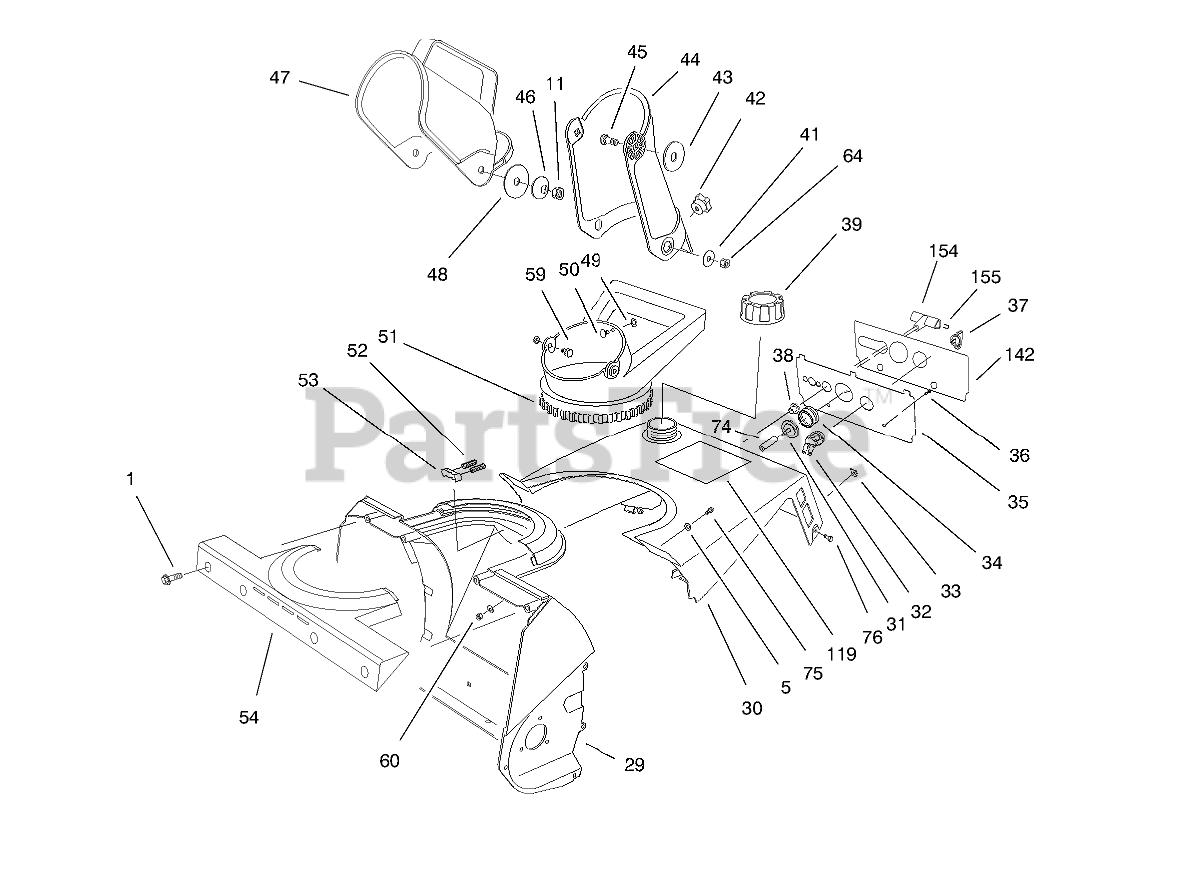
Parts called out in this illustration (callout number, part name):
1	SCREW-PLASTIC
5	WASHER-FLAT
11	NUT-LOCK, NI
29	HOUSING
30	Shroud-Upper
31	BODY-PRIMER
32	SWITCH
34	BULB-PRIMER
35	Panel-Control
36	SCREW-SHWH, THREAD FORMING
37	KEY-IGNITION
38	GUIDE-ROPE, STARTER
39	CAP-FUEL ASM
41	WASHER-FLAT
42	KNOB-CHUTE
43	WASHER-RUBBER
44	Chute
45	BOLT-CARR
46	WASHER-BELLEVILLE
47	DEFLECTOR-CHUTE
48	WASHER-FLAT
49	PUSHNUT-RETAINER, BOLT
50	SCREW-CARR
51	HANDLE-CHUTE
52	SPRING-COMPRESSION
53	DETENT-CHUTE
54	RETAINER-CHUTE
59	SCREW-HH
60	NUT-LOCK, NI
64	NUT-LOCK, NI
74	HOSE-PRIMER
75	SCREW-PPH
76	SCREW-THREAD FORMING
119	DECAL - POWERLITE REC.
142	Decal-Control Panel
154	HANDLE-STARTER
155	STAPLE-HANDLE
